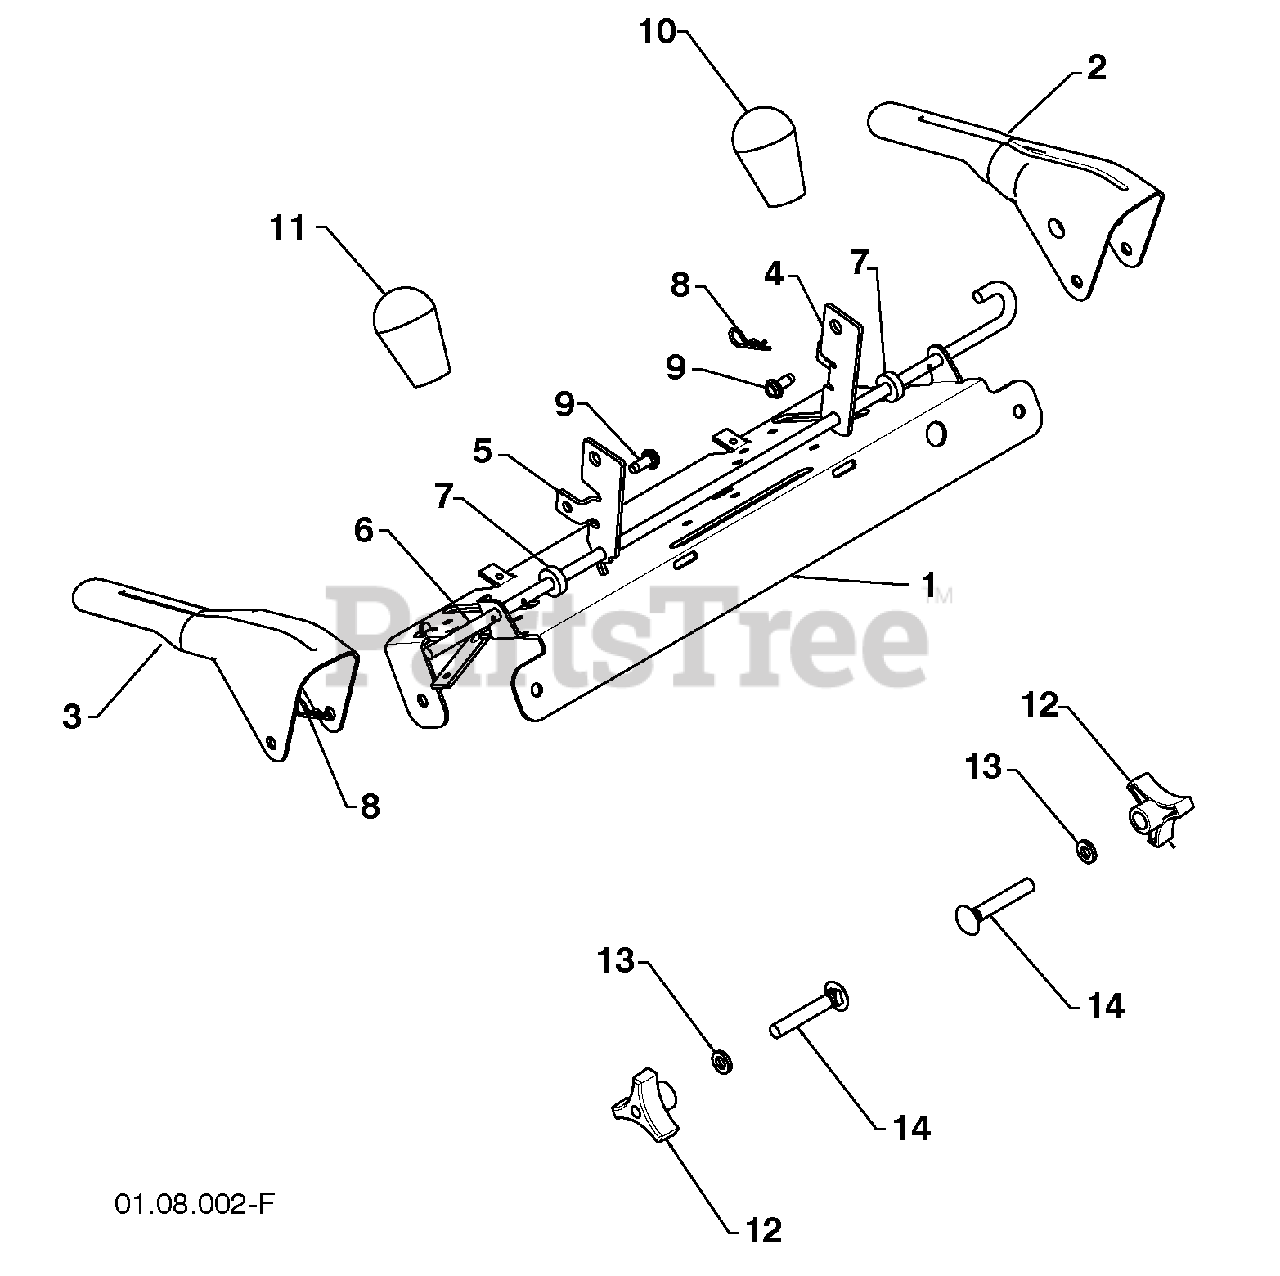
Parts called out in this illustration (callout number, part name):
1	CONTROL PANEL
2	CONTROL LEVER LH
3	CONTROL LEVER RH
4	TRACTION ROD ARM
5	IMPELLER ROD ARM
6	INTERLOCK ROD
8	RETAINER
9	SCREW 1/4-20 X .62
10	KNOB BLACK
11	KNOB RED
12	HANDLE KNOB
13	WASHER 3/8
14	CARRIAGE BOLT 3/8-16 X 2.25
